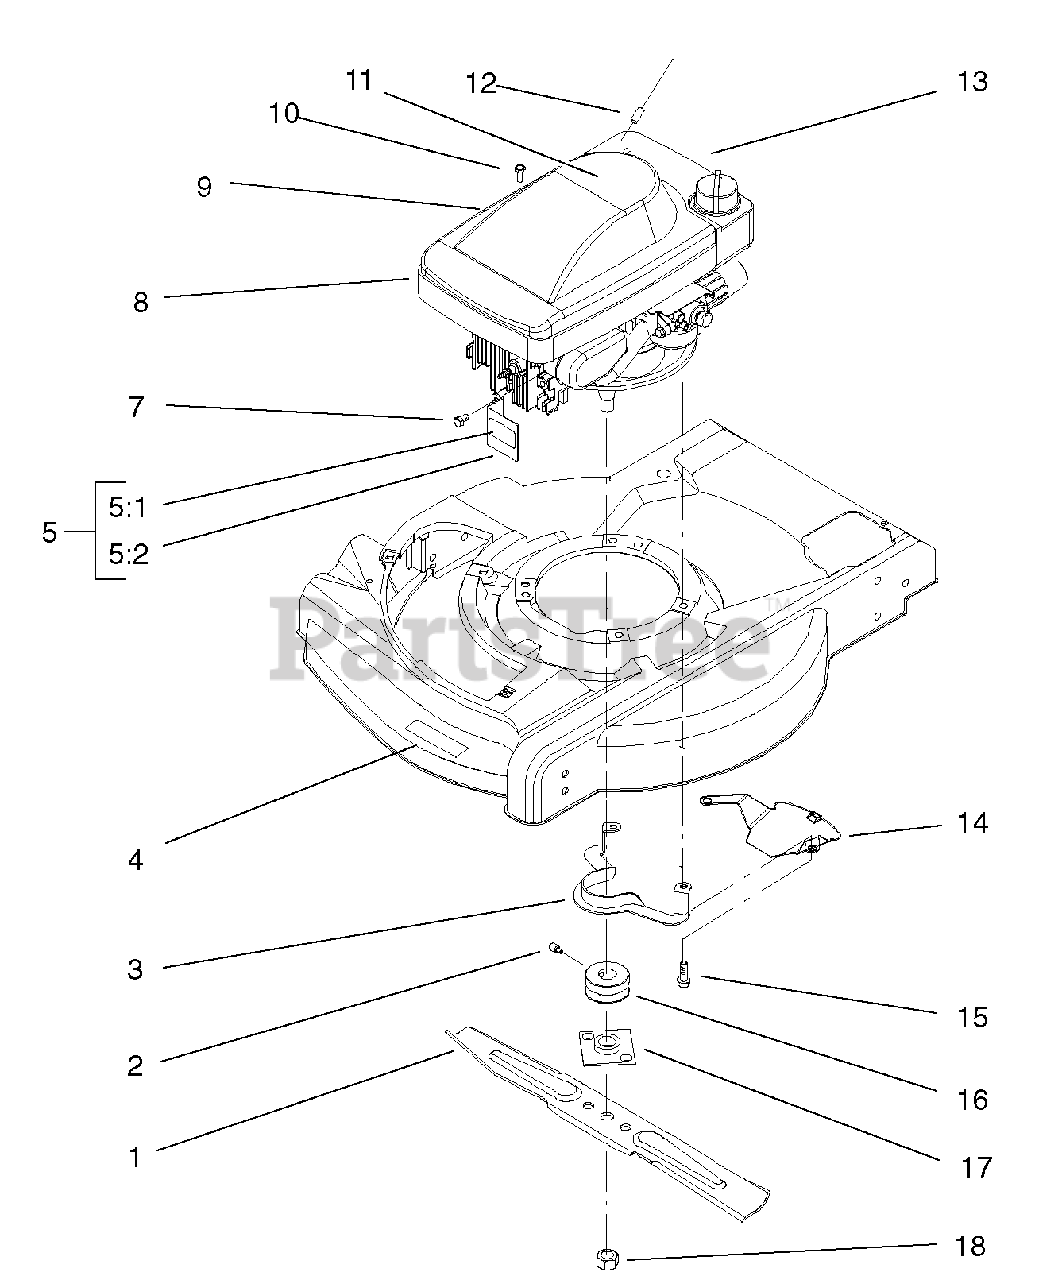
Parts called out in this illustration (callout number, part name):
2	SCREW-SET
3	GUIDE-BELT
4	DECAL-DECK
5	ASM - MUFFLER GUARD
5:1	DECAL-SURFACE, HOT
5:2	GUARD - MUFFLER
8	SHROUD - ENGINE
9	COVER - STARTER
10	SCREW - RECOIL COVER
11	DECAL-RECOIL
12	STOP-ROPE
13	Engine-Lev120 Ho,Zs
14	SHIELD - GRASS
15	SCREW-TAPTITE W/PATCH
17	BLADE RETAINER ASM
18	NUT-BLADE
